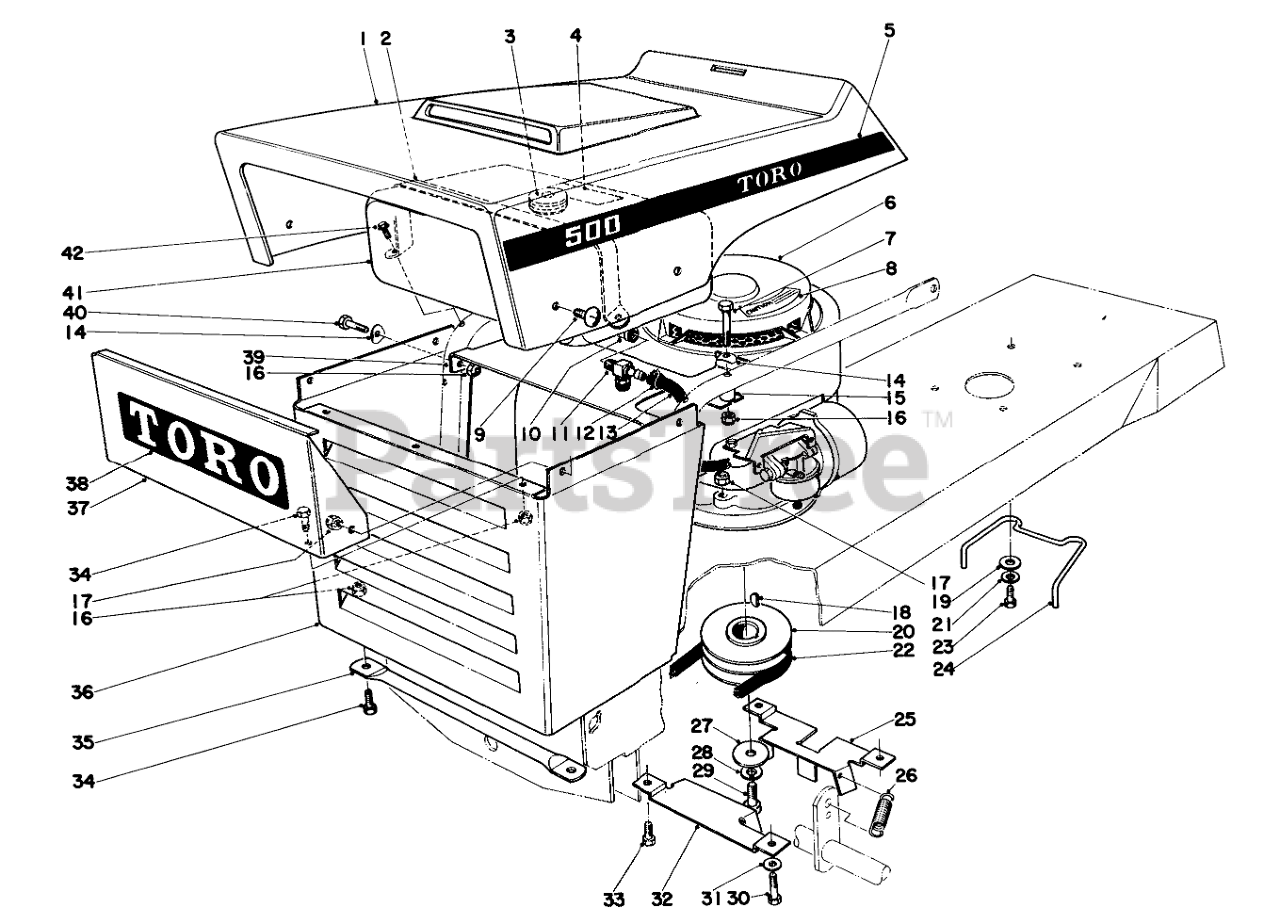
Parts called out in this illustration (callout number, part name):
2	Gas Tank Strap
3	GAS CAP
4	Decal
5	Decal Hood, Left (Model 57003)
6	Engine (Model 57003)
7	SCREW-HH
8	Decal, Engine Shroud (Model 57017)
9	Round Head Screw
10	Elbow
11	Shut Off Valve
12	Clamp
14	WASHER
15	Spacer
16	NUT-LOCK, CONE
17	NUT-LOCK, CONE
18	KEY-WOODRUFF
19	WASHER-FLAT
20	Engine Pulley
21	WASHER-LOCK
22	ENGINE BELT
23	SCREW-HH
24	Belt Retainer
25	Belt Guide
26	Spring Tension
27	Washer
28	WASHER-LOCK
29	SCREW-HH
30	SCREW-HH
31	WASHER-PLAIN
32	Belt Guide
33	SCREW-HH
34	SCREW-HH
35	Rod Grille Mount
36	Grille
37	Panel Grille
38	Decal-Grille Panel
39	Tray Gas Tank
40	SCREW-HH
41	GAS TANK
42	Screw
